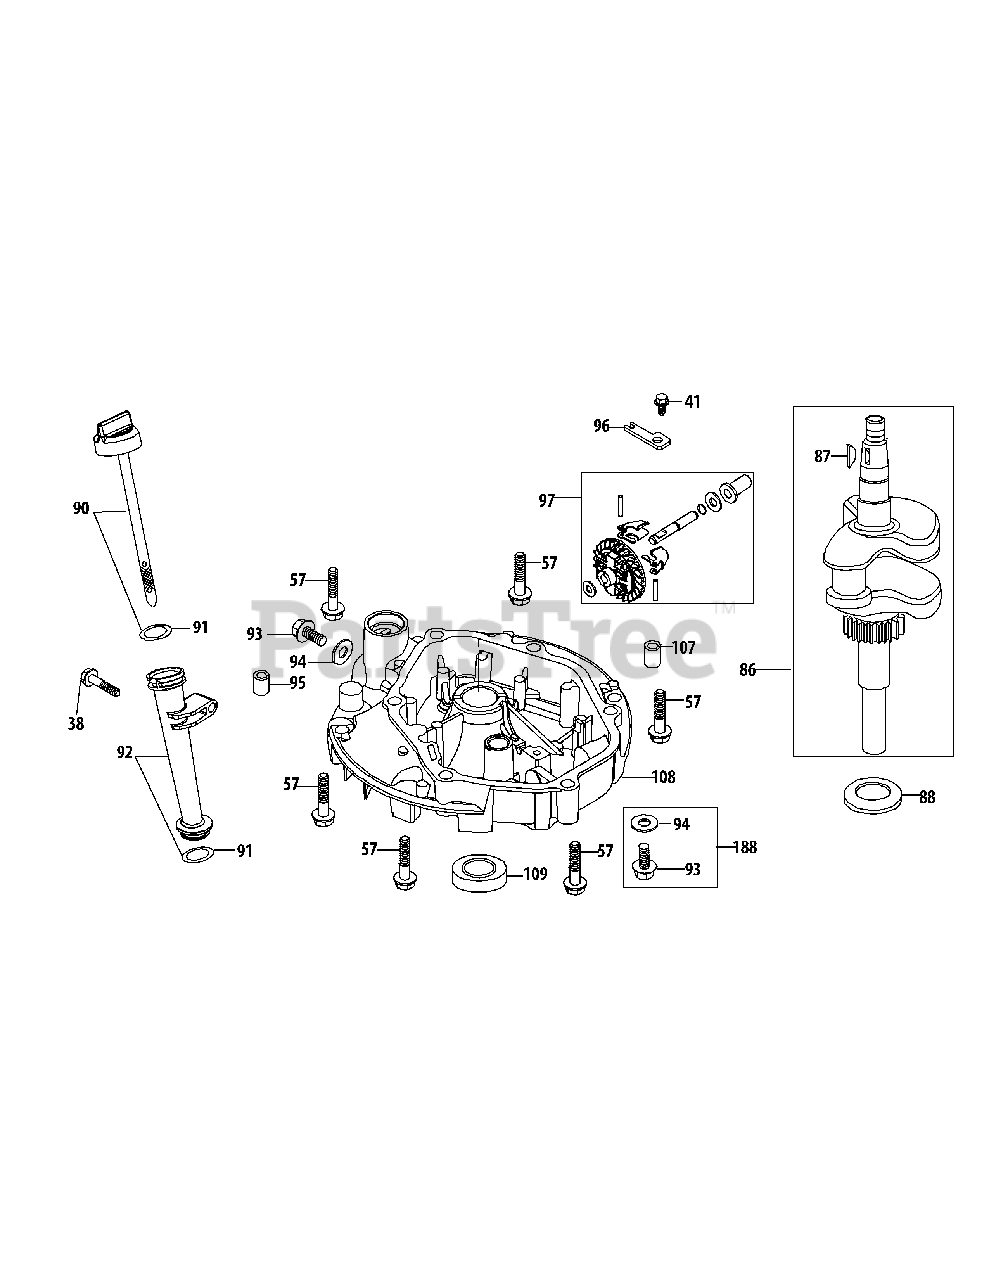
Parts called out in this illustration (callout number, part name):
38	Bolt M6X35
41	Bolt M6X14 Multi-Purpose
57	Bolt M8X50
86	Crankshaft Assembly
87	Woodruff Key
88	Crankshaft Thrust Washer
90	Dipstick Assembly
91	Dipstick / Oil Fill Tube O-Ring
92	Oil Filler Tube Assemlby
93	Oil Drain Plug
94	Oil Drain Plug Washer
95	Crankcase Cover Dowel Pin 9×14
96	Governor Gear Mounting Plate
97	Governor Gear/Shaft Assembly
107	Crankcase Cover Dowel Pin 7×14
108	Crankcase Cover
109	Lower Crankshaft Seal
188	Oil Drain Plug & Washer Ass'y
